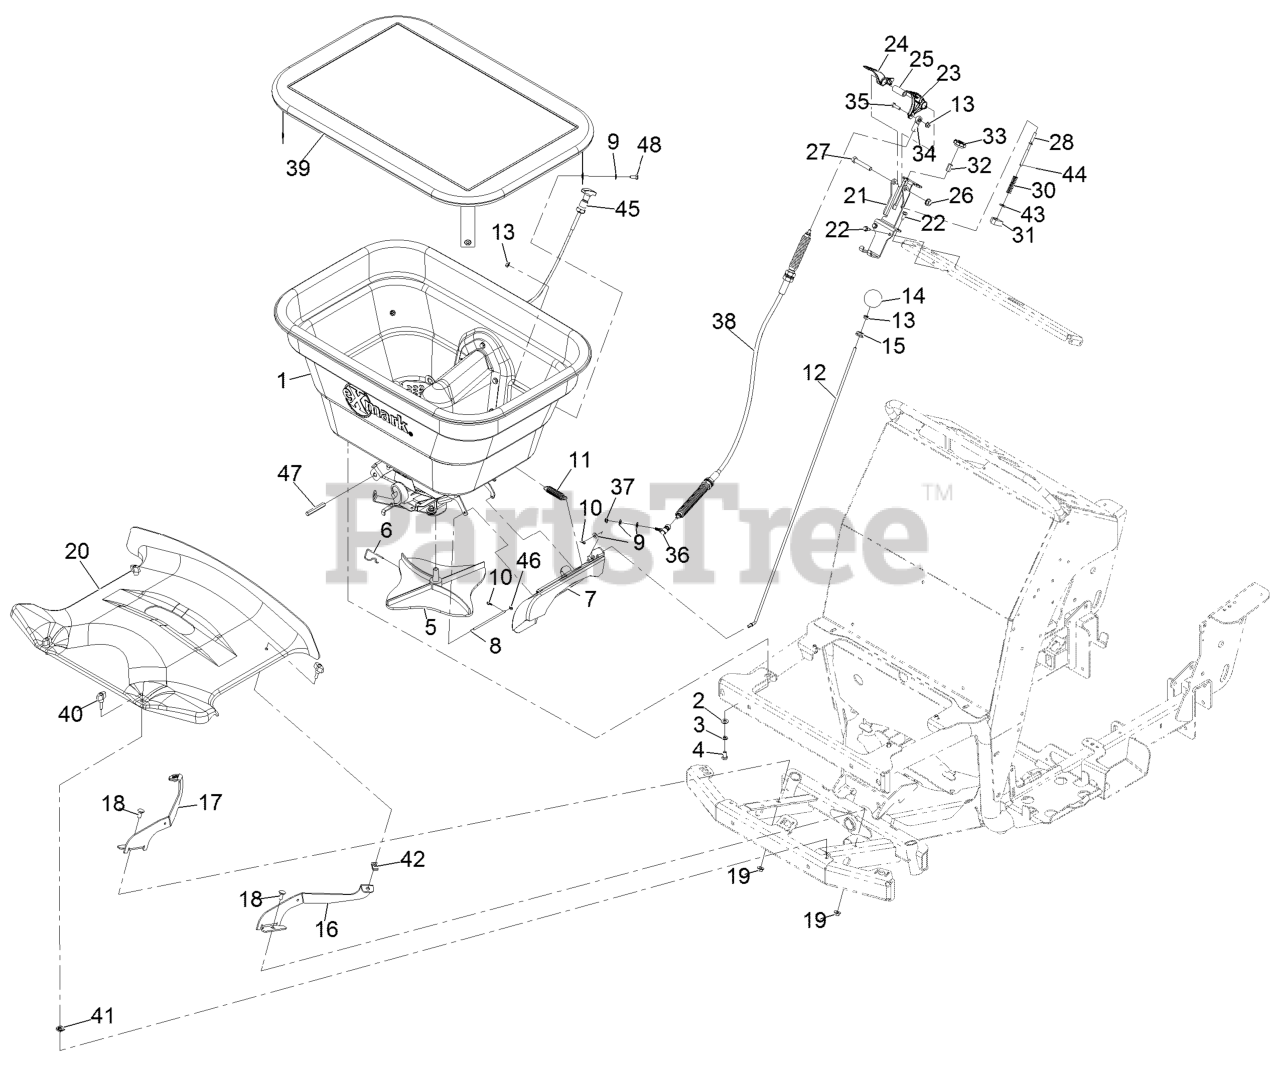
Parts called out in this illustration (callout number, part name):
1	Spreader Hopper ASM
3	WASHER-LOCK
4	SCREW-HH
5	SPINNER-SPREADER
6	CLIP-SPINNER
7	Side Deflector ASM
8	PIN-DEFLECTOR
9	WASHER-FLAT
10	PIN-COTTER, HAIR
11	SPRING-EXTENSION
12	ROD-CONTROL, DEFLECTOR
14	KNOB-RATE, FLOW
15	GROMMET
16	BRACKET-COVER, FRONT (LH)
17	BRACKET-COVER, FRONT (RH)
18	SCREW-CARR
20	COVER-FRONT, SPREADER/SPR
21	MOUNT-HANDLE
22	SCREW-HWH
23	LEVER-SPREAD, WIDE
24	LEVER-SPREAD, NARROW
27	SCREW-HH
28	LINK-ADJUST, NARROW
30	SPRING-COMPRESSION, BAIL
31	STOP-SPREAD, NARROW
32	NUT-COUPLER
34	ROD END-BALL JOINT
35	SCREW-HH
36	BALL-JOINT
37	NUT-HEX, NI
39	COVER-HOPPER
41	NUT-RETAINER, U STYLE
42	NUT-RETAINER
43	WASHER-FLAT
44	PIN-COTTER
45	CABLE-CONTROL, TURN LOCK
46	WASHER-FLAT
47	POST-HEX, DIFFUSER GUIDE
48	SCREW-HH
